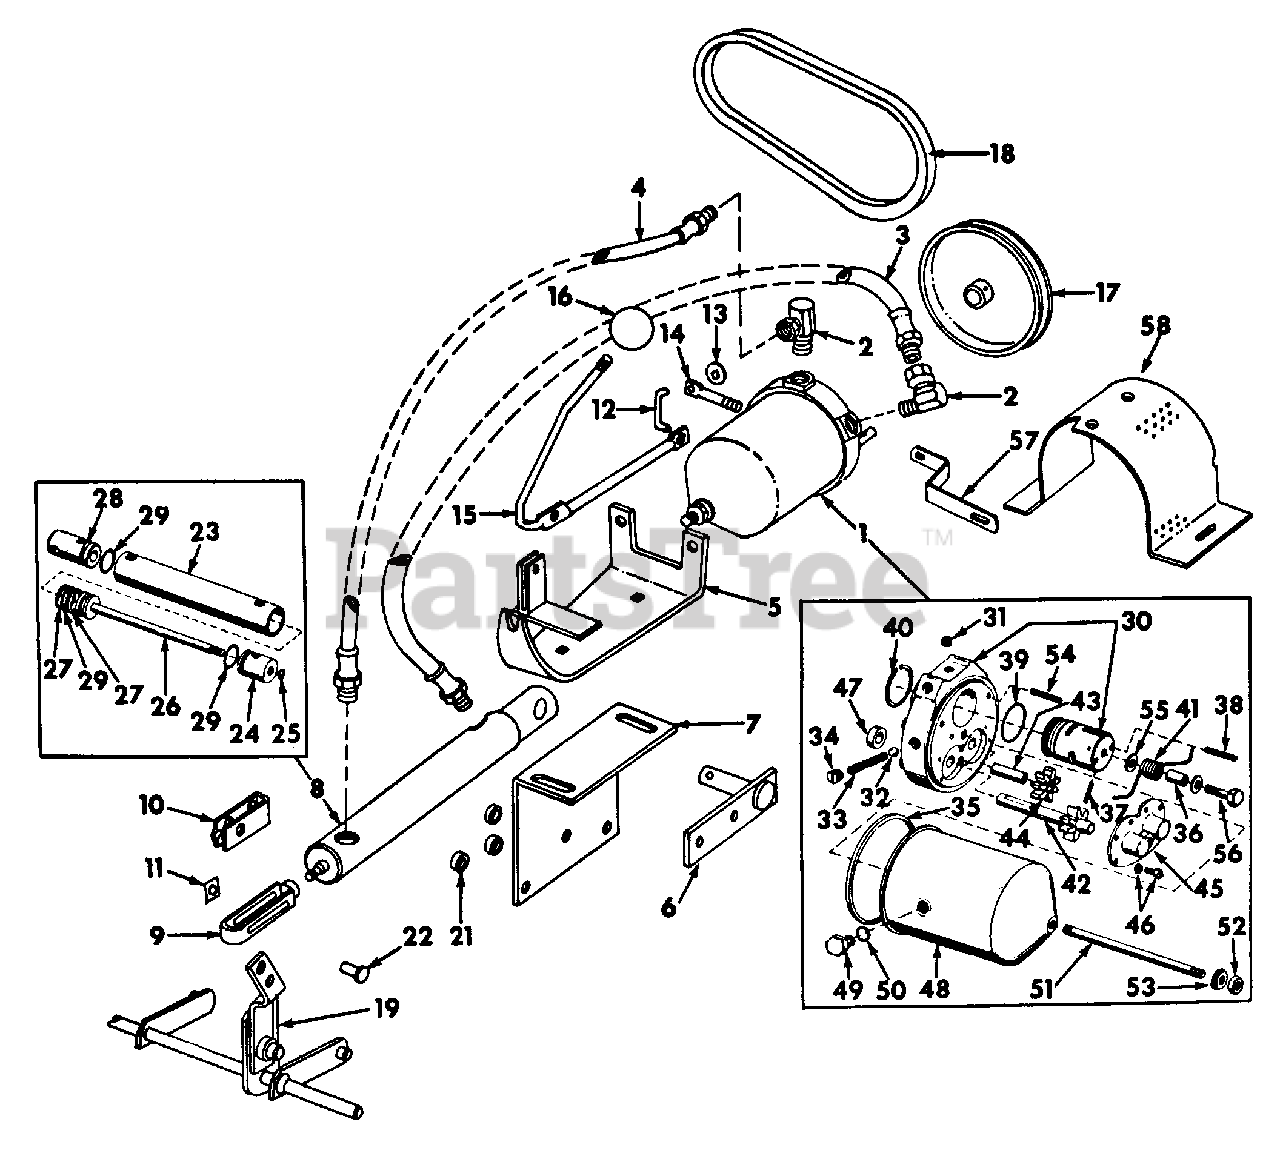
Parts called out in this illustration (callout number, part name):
1	Pump Assy, Hyd
2	Fitting, Hyd Pump 90 Deg Union
3	Hose Assy, Hyd 9 In.
4	Hose Assy, Hyd 14 In.
5	Bracket Assy, Hyd Pump Mounting
6	Bracket Assy, Hyd Cyl Support
7	Bracket, Frame Mounting
8	Cylinder Assy, Hyd
9	Clevis Assy, Hyd Cyl End
10	Clip, Cyl End Clevis Rivet Locking
11	Nut, Locking Clip Push-On Type
12	Rod, Hyd Pump Actuator Control
13	Nut, Actuator Control Rod Push-On Type
14	Extension Pump Spool
15	Rod, Control Lever
16	Knob, Control Lever Rod
17	Pulley, Driven
18	Belt, Drive Pulley
19	Rockshaft Assy, Hyd Lift
21	Spacer, Frame Mounting Bracket
22	Rivet, 1/2 X 1-1/4 F-Hd Solid
23	Tube, Hydraulic Cylinder
24	Guide, Hydraulic Cylinder
25	O-Ring, 5/8 X .813 X 3/32
26	Piston & Rod, Hydraulic Cylinder
27	Washer, Piston & Rob Backup
28	Head, Hydraulic Cylinder
29	O-Ring, 1-1/4 X 1-1/2 X 1/8
30	Body & Valve, Hyd Pump
31	Plug, 1/8-27 Automotive Hex Soc Hd Pipe
32	Ball, 5/16 Cr-Stl
33	Spring, Hyd Pump Body
34	Plug, Pump Body Spring Retaining
35	Gasket, Hyd Pump Body
36	Spacer, Spring Sleeve
37	Pin, 5/32 X 7/8 Slt Spring
38	Pin, 1/8 X 1-1/4 Slt Spring
39	O-Ring, 1-1/4 X 1-1/2 X 1/8
40	Ring, Hyd Pump Spool Valve Snap
41	Spring, Hyd Pump Spool Valve
42	Shaft Assy, Hyd Pump Drive
43	Shaft, Hyd Pump Idler
44	Gear, Hyd Pump Idler Shaft
45	Cover, Hyd Pump Shaft
46	Screw w/Spring Lock Washer, 10-13 X 7/16 Slt Fil Hd Mach
47	Seal, Hyd Pump Drive Shaft
48	Reservoir, Hyd Pump
49	Screw, 1/2-20 X 1/2 Hex Hd Cap
50	Washer Hyd Pump Reservoir Fiber
51	Stud, Hyd Pump Reservoir
52	Nut, 3/8-16 Hex Jam
53	Washer, Hyd Pump Reservoir Stud
54	Pin, 3/16 X 1-1/2 Slt Spring
55	Washer, 11/32 X 11/16 X .065
56	Screw w/Nylon Pellet, 5/16-18 X 1-1/8 Hex Hd Cap
57	Arm, Support
58	Shield, Clutch
